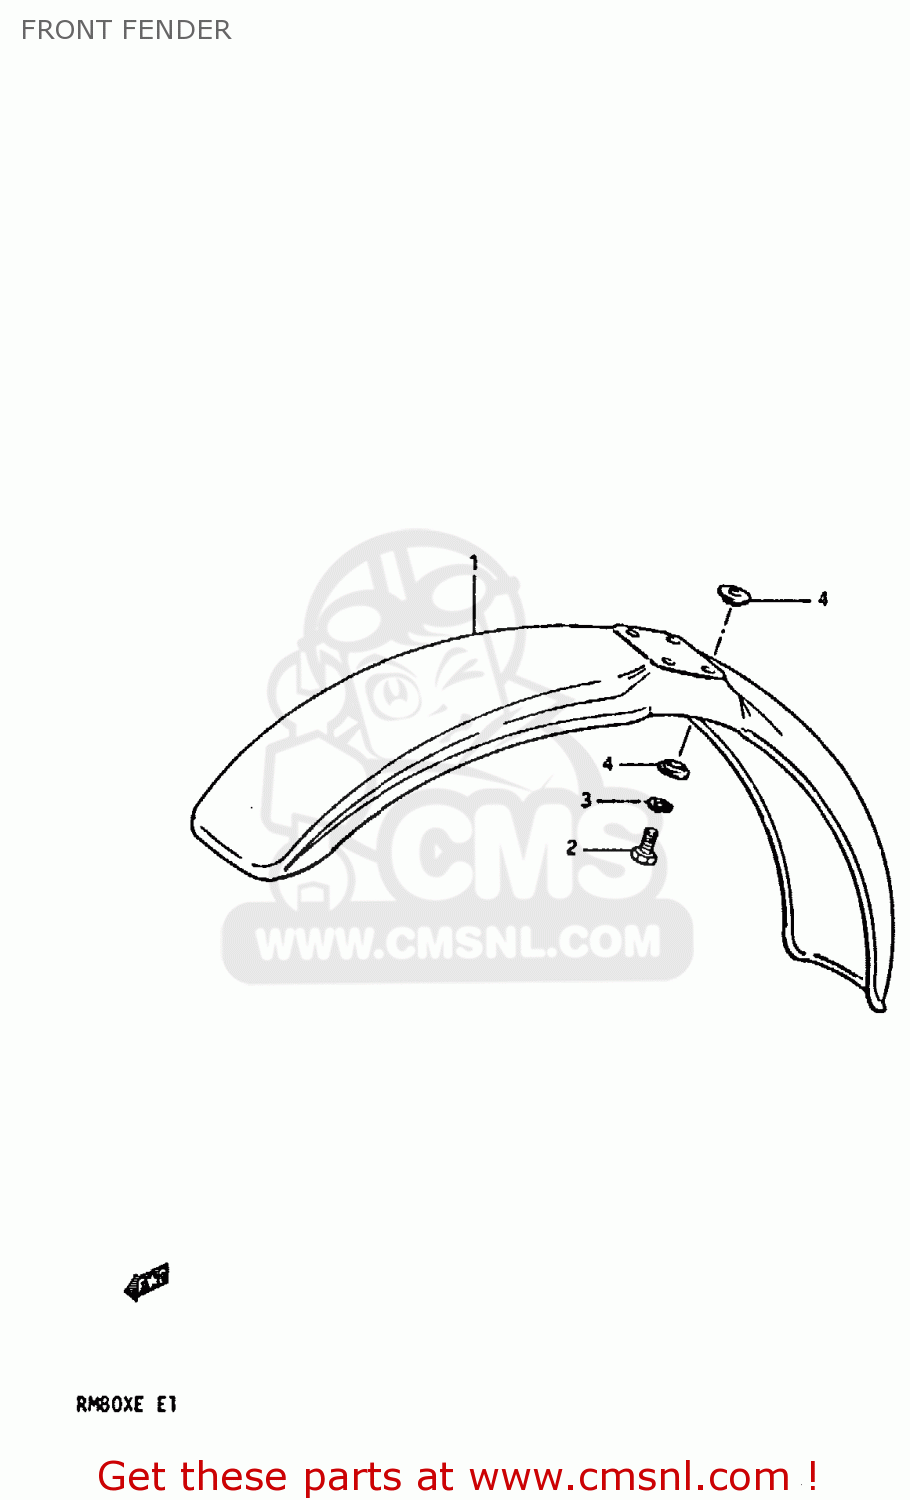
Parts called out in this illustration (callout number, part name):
1	FENDER,FRONT
2	BOLT, UPPER
3	LOCK WASHER
4	SPACER
